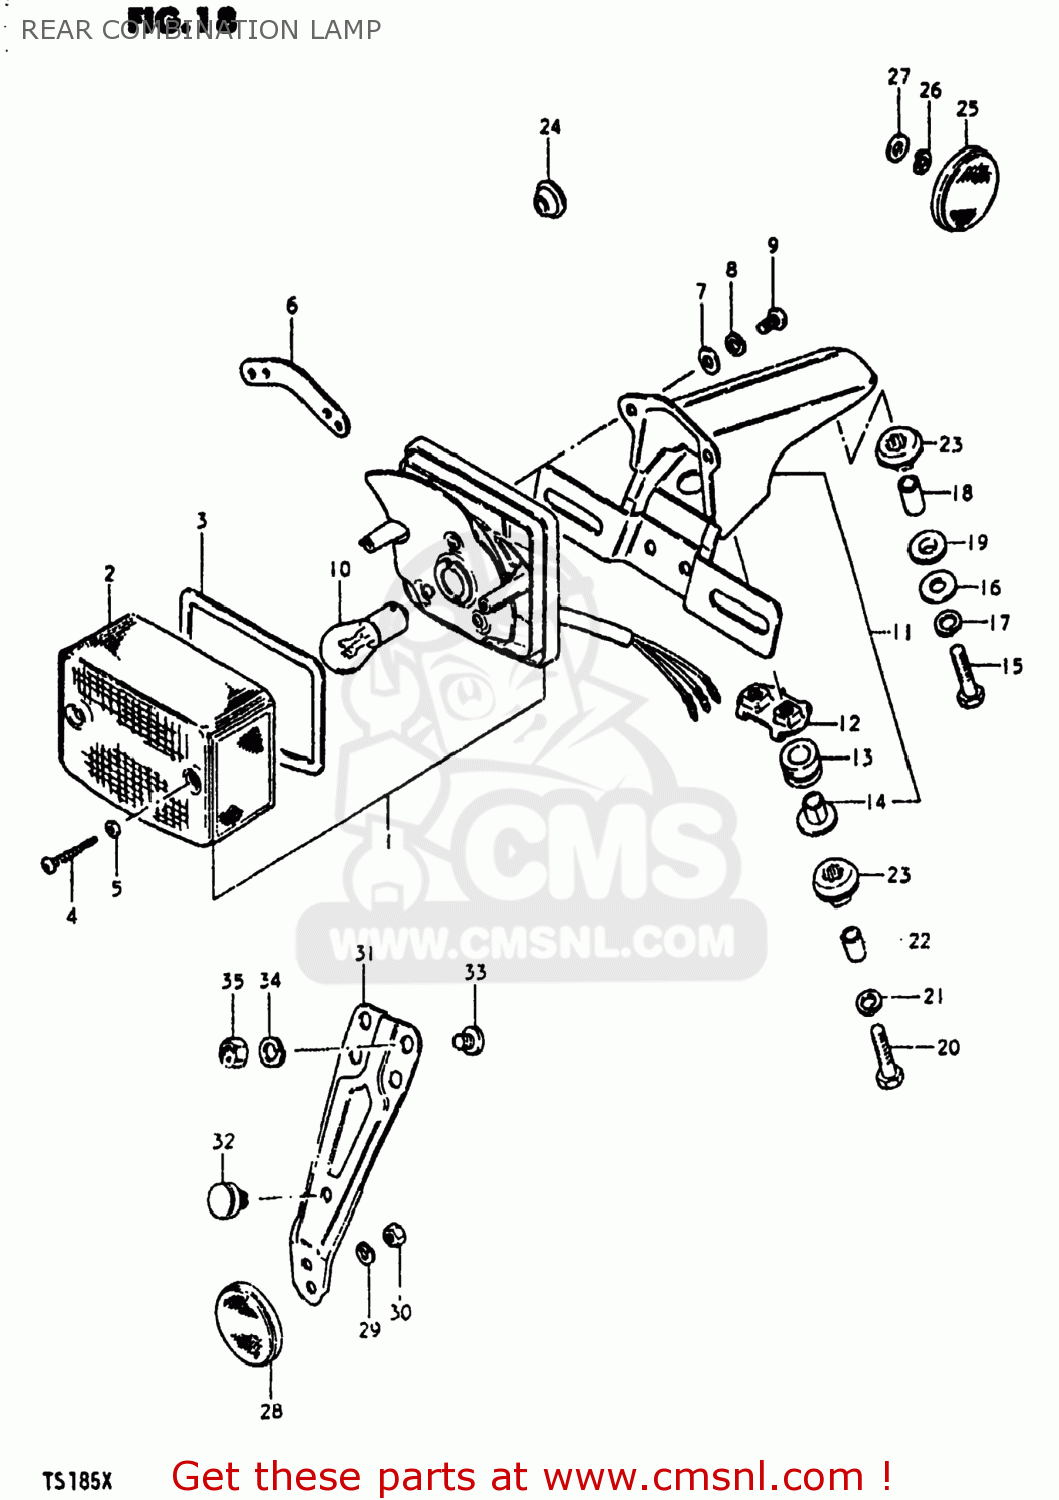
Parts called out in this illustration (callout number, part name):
1	LAMP UNIT,REAR COMBINATION
2	LENS
3	GASKET (NAS)
4	BOLT
5	GASKET (NAS)
6	PLATE,REAR COMBINATION LAMP
7	WASHER
8	LOCK WASHER
9	SCREW
10	BULB(6V32/3CP,STANLEY)
11	BRACKET UNIT,TAIL LAMP
12	PLATE
13	CUSHION
14	SPACER
15	BOLT
16	WASHER (6.5X20X1.2)
17	LOCK WASHER
18	SPACER
19	CUSHION
20	BOLT 6X40
21	LOCK WASHER
22	SPACER (6.8X10X11.5)
23	CUSHION
24	GROMMET
25	REFLEX REFLECTOR,FR
26	LOCK WASHER
27	WASHER
28	REFLEX REFLECTOR,RR
29	LOCK WASHER
30	NUT
31	BRACKET
32	CUSHION
33	SCREW
34	LOCK WASHER
35	NUT
